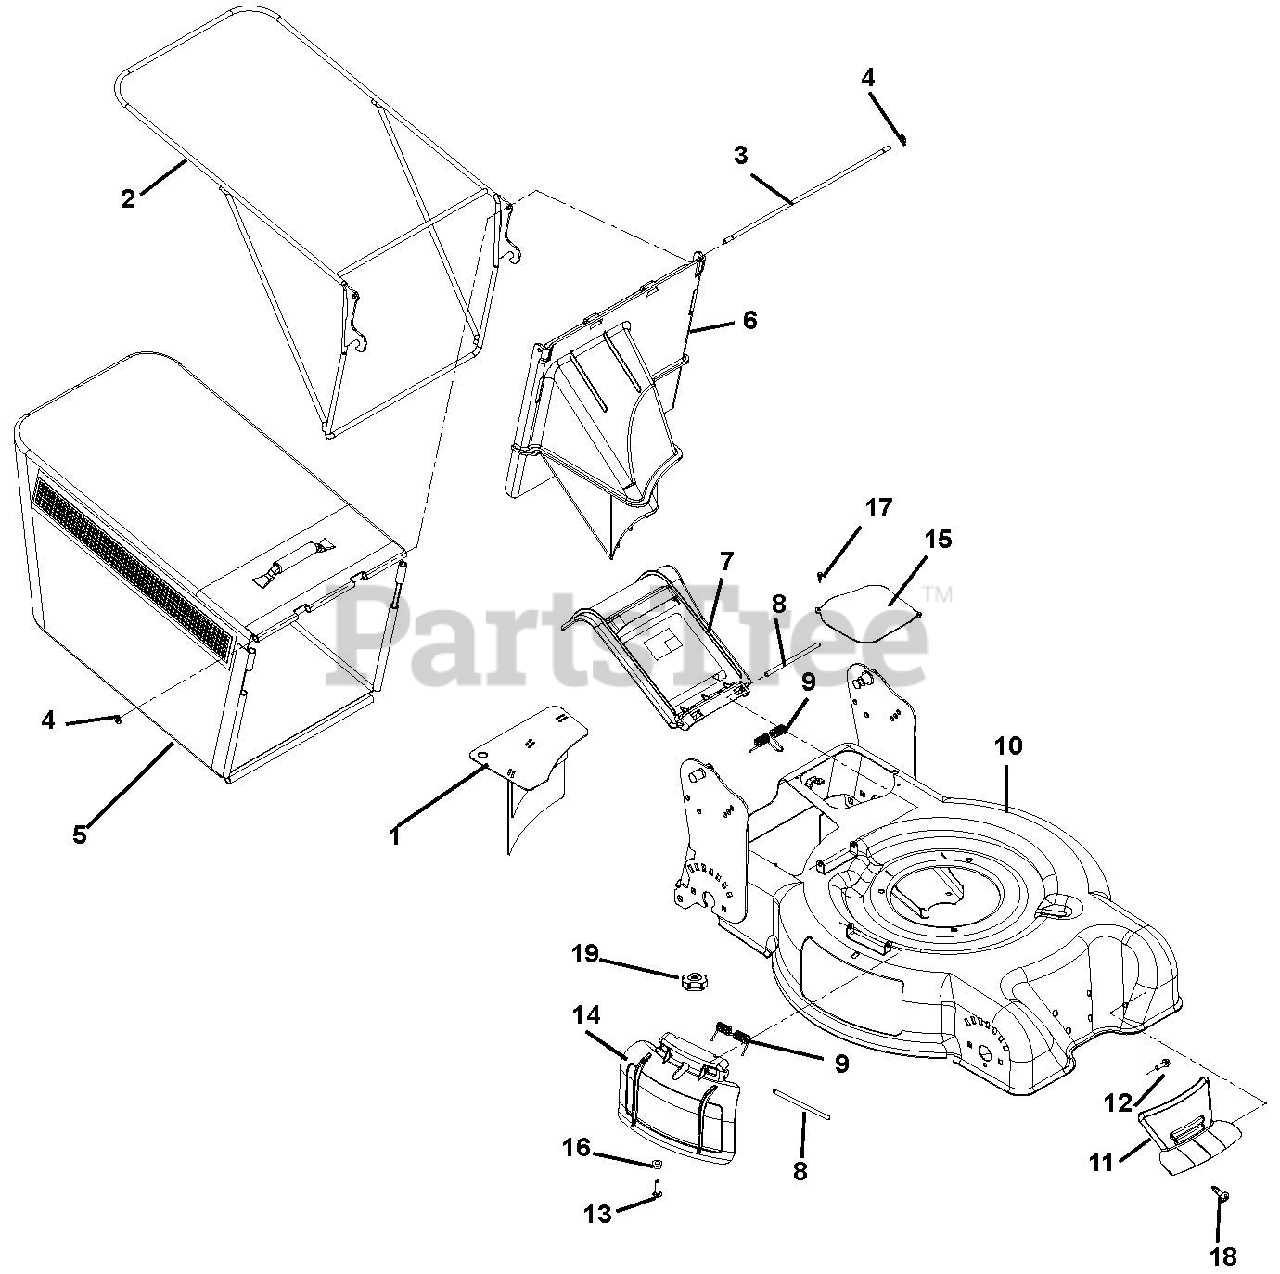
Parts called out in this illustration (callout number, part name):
1	PLUG, MULCH (STEEL)
2	BAGGER FRAME
3	ROD, HINGE
4	NUT-PUSH .25X.50 O.D.
5	WBLM, ARIENS BAGGER
6	BAGGER DOOR
7	REAR DISCHARGE COVER
8	PIN, HINGE
9	TORSION SPRING
10	21" DECK WELDMENT
11	GRILL INSERT
12	SCR-TAP 12-12X.75 HI-LOW YZ
13	@BLT-RDHDSQNK .25-20X.75 G5YZ
14	MULCH COVER
15	COVER, TRANSMISSION ACCESS
16	NUT-PUSH .25X.50 O.D.
17	@SCR-TAP 10-24X.375 HWH YZ TR
18	SCREW, SELF DRILL/TAP
19	KNOB-CLAMPING, .250-20 NYLOC
